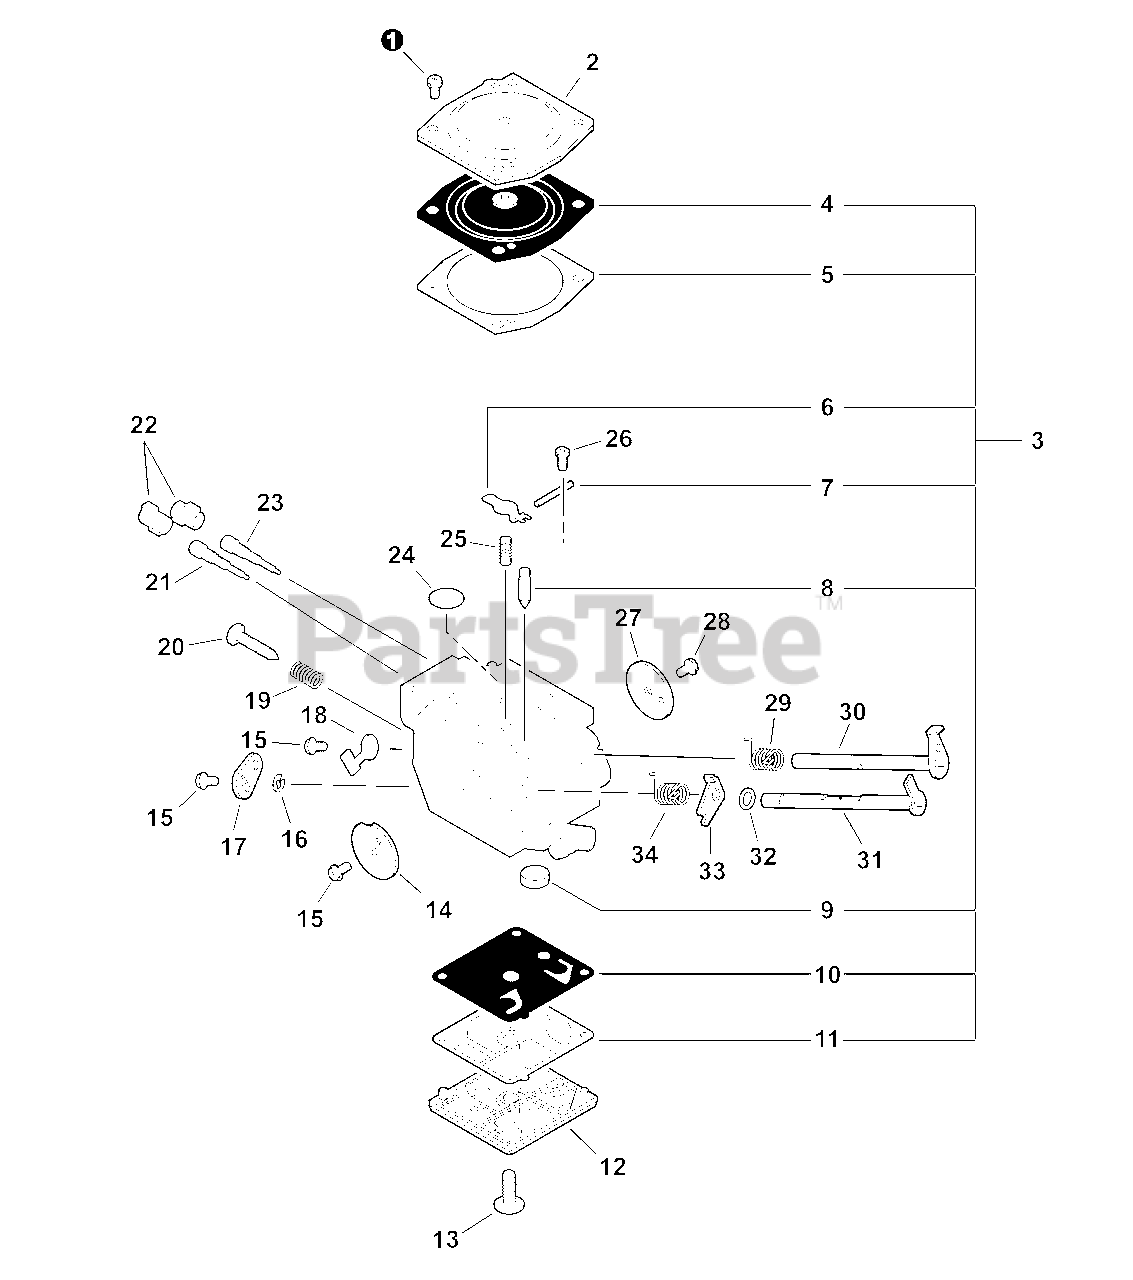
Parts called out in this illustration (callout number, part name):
2	COVER, METERING DIAPHRAGM
3	REPAIR KIT
4	DIAPHRAGM, METERING
5	GASKET, METERING
6	LEVER, METERING
7	PIN, METERING LEVER
8	VALVE, INLET NEEDLE
9	STRAINER
10	DIAPHRAGM, PUMP
11	GASKET, PUMP
12	COVER, FUEL PUMP
14	VALVE, THROTTLE
17	LEVER, CHOKE
18	STOP, THROTTLE
19	SPRING, IDLE ADJUST
20	SCREW, IDLE ADJUST
21	NEEDLE, HIGH SPEED
22	CAP, LIMITER
23	NEEDLE, MIXTURE
24	PLUG, WELCH
26	SCREW, METERING LEVER PIN
27	VALVE, THROTTLE
29	SPRING, THROTTLE RETURN
30	SHAFT, THROTTLE
31	SHAFT, CHOKE
33	LEVER, FAST IDLE
34	SPRING, CHOKE RETURN
